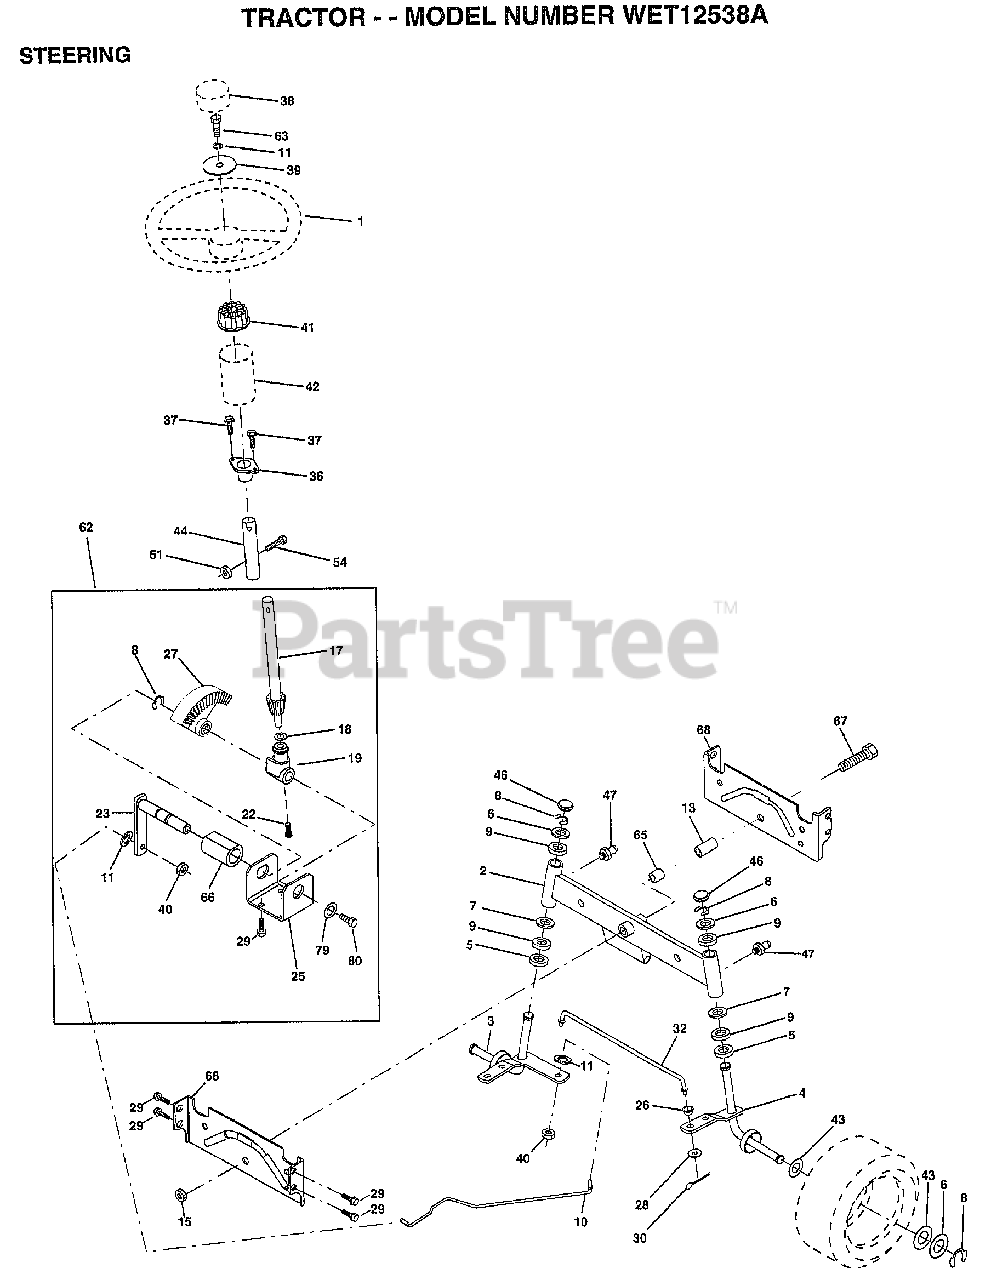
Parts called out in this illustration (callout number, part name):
1	WHEEL STR AYP BLK
2	AXLE ASM
3	SPINDLE.ASM.LH
4	"SPINDLE ASM,RH"
5	WASHER .T
6	WASHER
7	WASHER
8	RING
9	COL. SRTG. BEAR.
10	DRAGLINK-STAMPED
11	LOCKWASHER
13	BEARING AXLE
15	"NUT-LOC,FLANGE LT"
17	SHAFT ASM STEERIN
18	THRUST WASHER
19	SUPPORT.SHAFT.STEER
22	SCREW.HX.WSH.HD
23	SHAFT.ASM.PITMAN
25	BRKT-STEERING
26	BUSHING.DRAGLINK
27	GEAR SECTOR
28	WASHER
29	SCREW
30	COTTER PIN
32	TIE ROD
36	BUSHING.STEERING
37	"SCREW-TT,10-32 FL"
38	CAP STEER AYP
39	WASHER T
40	GRIPCO NUT
41	ADAPTER LT
42	BOOT.STEER.PL
43	WASHER
44	EXT SHAFT STEERIN
46	CAP
47	ZERK M
51	NUT
54	BOLT
62	KIT.STEER.ASM
63	BOLT
65	SPACER AXLE
66	"BEARING-ARM,PITMA"
67	BOLT
68	BRACE AXLE
79	WASHER
80	BOLT.HX.NYLON3/8-16X3/
